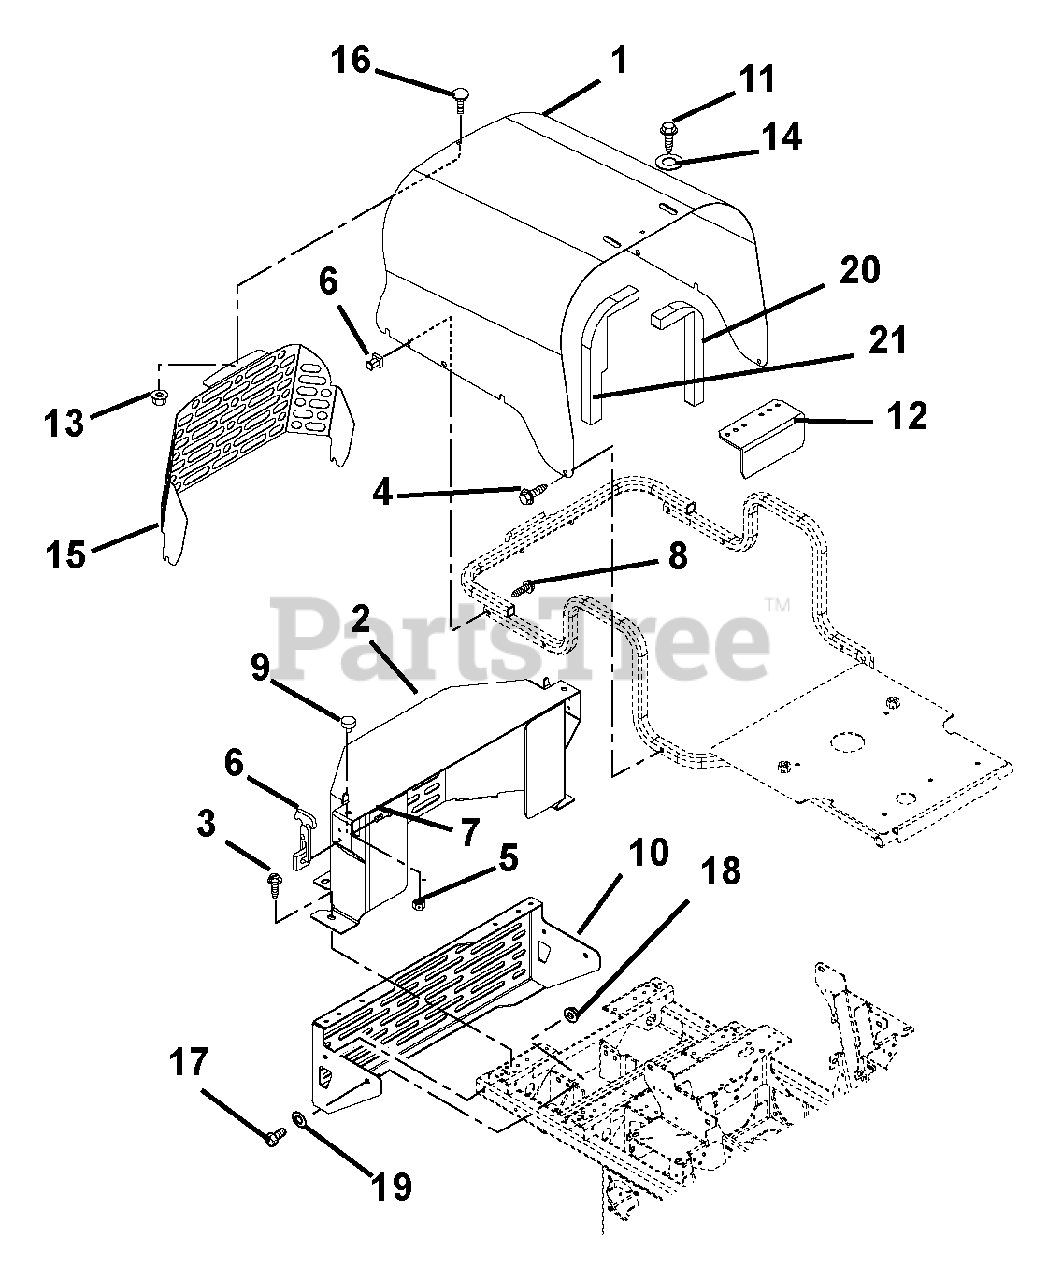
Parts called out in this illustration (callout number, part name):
2	Diesel Belt Guard
3	Screw, Tapping .38-16 x .75 Hex Washer Head
4	Screw, Tapping .38-16 x .50 Hex Washer Head
5	Nut, Spin Lock, Flange .312-18
6	Latch, Rubber
7	Screw, Machine 10-24 x .50 Hex Washer Head
8	Screw, Machine 10-24 x 1.50 Hex Washer Head
9	Bumper, Rubber
10	Bumper, Weldment, Rear Diesel
11	Screw, Tapping .25-20 x .50 Hex Washer Head
12	Guard, Radiator Cap
13	Nut, Locking Top Flange .25-20
14	Washer, Flat Steel .281 x .62 x .065
15	Guard, Hood
16	Bolt, Round Head Square Neck .25-20 x .50 Grade 5
17	Bolt, Hex .38-16 x 2.75 Grade 5
18	Nut, Locking Top Flange .38-16
19	Washer, Flat Steel .406 x .812 x.065
20	Dam, Left Side Foam Air
21	Dam, Right Side Foam Air
